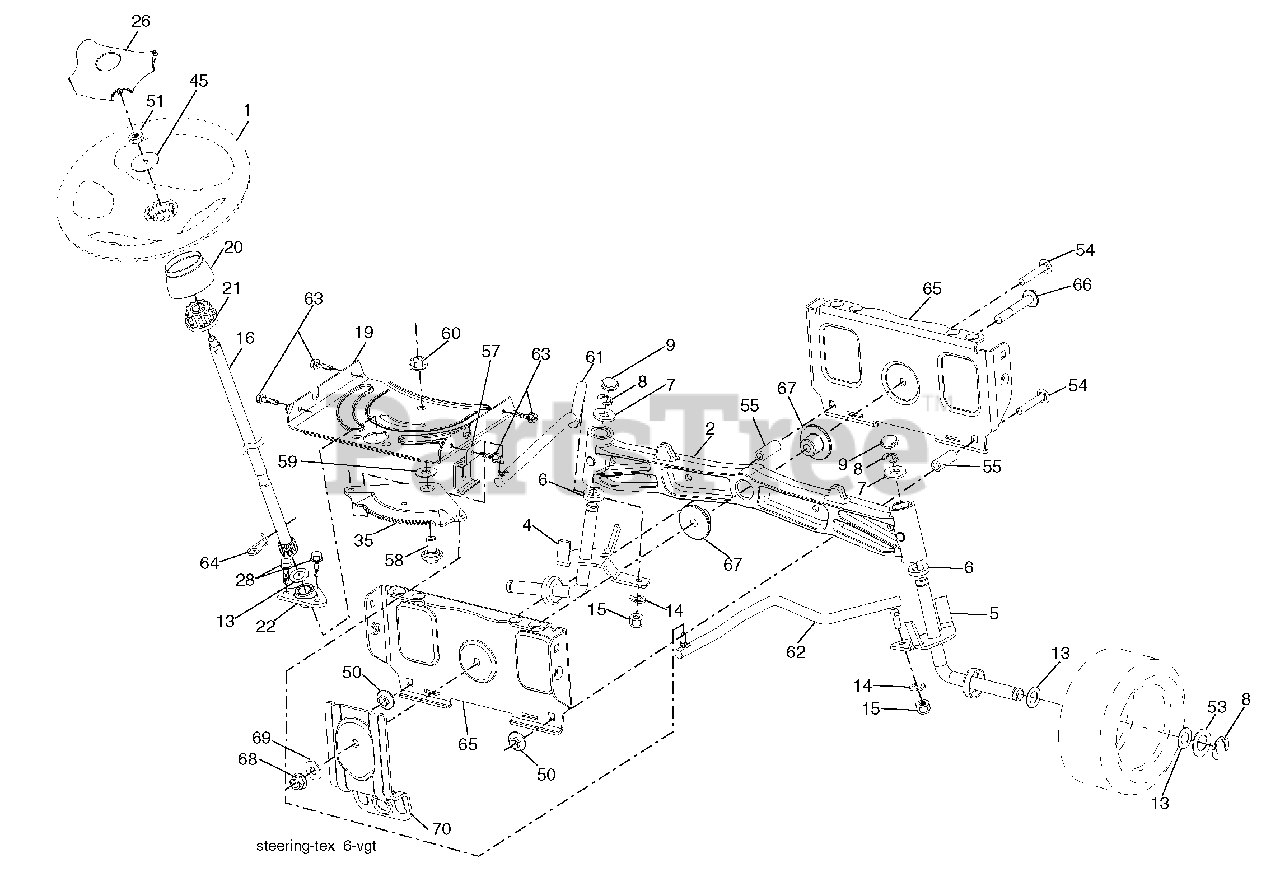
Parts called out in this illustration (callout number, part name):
1	Wheel, Steering
2	Axle Asm., Front
4	Spindle Asm., LH
5	Spindle Asm., RH
6	Bearing, Race Thrust Harden
7	Washer 25/32 x 1-5/8 x 16 Ga.
8	Ring, Klip #T5304-75
9	Cap, Spindle
13	Washer 25/32 x 1-1/4 x 16 Ga.
14	Washer, Lock Hvy Hlcl Spr 3/8
15	Nut, Crown Lock 3/8-24 unf
16	Shaft Steering
19	Plate Steering
20	Boot, Steering
21	Adapter, Wheel Steering
22	Bushing, Strg. Blk
26	Insert, Wheel Steering
28	Screw 3/8-16 x 3/4
35	Gear, Sector Plate
45	Washer 9/16 x 2-3/8 x 12 Ga.
50	Nut Lock Flg. 3/8-16 unc
51	Nut Hex Jam Toplock 1/2-20 unf
53	Washer Hardened .793 x 1.637 x .060
54	Bolt Hex Hs 3/8-16 unc x 2-1/4
55	Spacer Brace Axle
57	Bracket Upstop
58	Bolt Shoulder Sector Pivot CFM
59	Washer Thrust Sector Steering
60	Nut Flange Lock 5/8-11
61	Draglink LH
62	Draglink, RH
63	Screw 5/16-18 x 3/4
64	Retainer Clip Spring Steering
65	Brace Axle Front
66	Bolt Hex Fghd 7/16-14 x 3 Serr
67	Bushing PM Front Axle
68	Nut Lock Flange 7/16-14 Gr. 5
69	Washer 1.5 x .505 x .118
70	Bracket Deck Susp. Front
